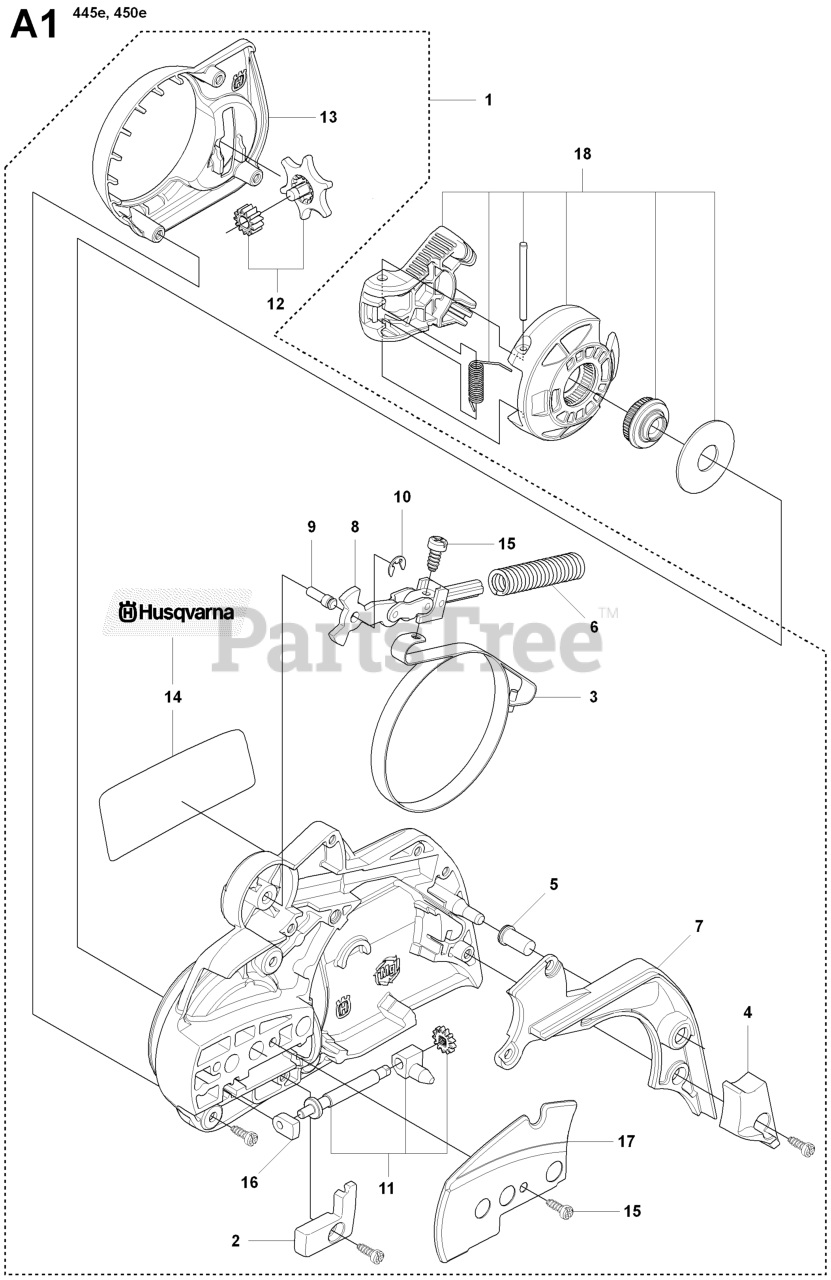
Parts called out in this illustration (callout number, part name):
1	CLUTCH HOUSING COMPLETE
2	COVER
3	BRAKE BAND
4	WEAR GUARD, CHAIN
7	COVER, CHAIN BRAKE
11	CHAIN TENSIONER SCREW, COMP.
12	CHAIN TENSIONER WHEEL, COMP.
13	HEAT SHIELD
14	DECAL, CLUTCH HOUSING
16	RP BEARING SLEEVE
18	KNOB, COMPLETE
